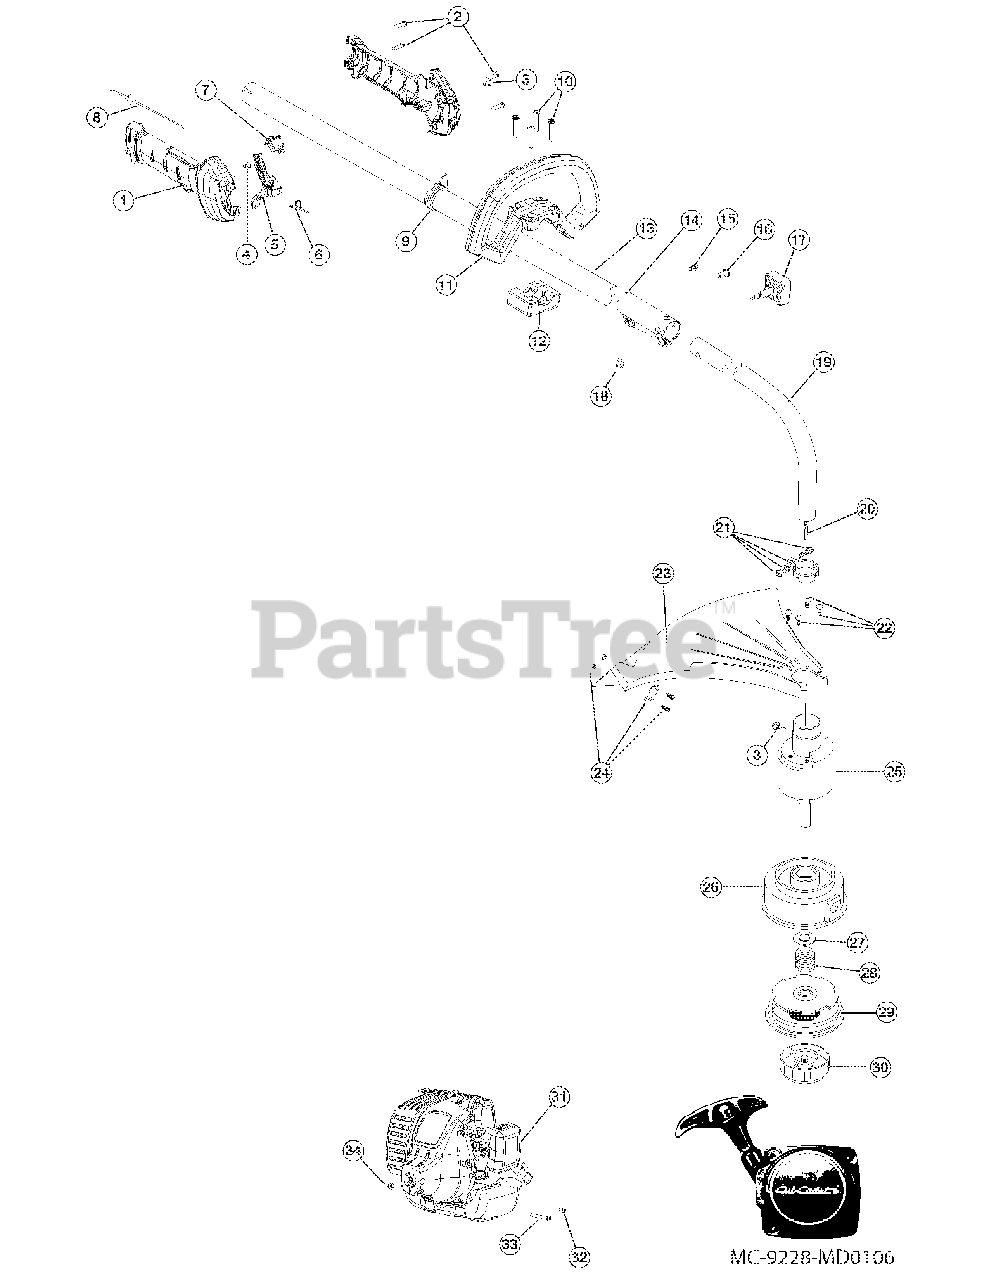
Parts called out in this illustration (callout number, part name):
1	Throttle Grip Assembly (includes2-7)
3	Anti-Rotation Screw
4	Throttle Cable Mounting Screw
5	Throttle Trigger
6	Throttle Trigger Spring
8	Throttle Cable
9	Harness Clip
12	D-Handle Base
13	Upper Drive Shaft Assembly
14	Split Boom Coupler Assembly (includes15-18)
17	Knob (includes18)
18	Nut
19	Lower Drive Shaft Housing Assembly
20	Lower Flex Shaft
21	Lower Clamp Assembly
22	Shield Mounting Screws
23	Shield Assembly (includes24)
24	Blade Assembly
25	Bushing Housing Assembly w/shaft
25	Bushing Housing w/o shaft
26	Outer Spool assembly (includes27)
29	Inner Reel
30	Bump Head Knob Assembly
31	Engine Assembly
32	Anti-Rotation Screw
33	Clamping Screw
34	Nut
